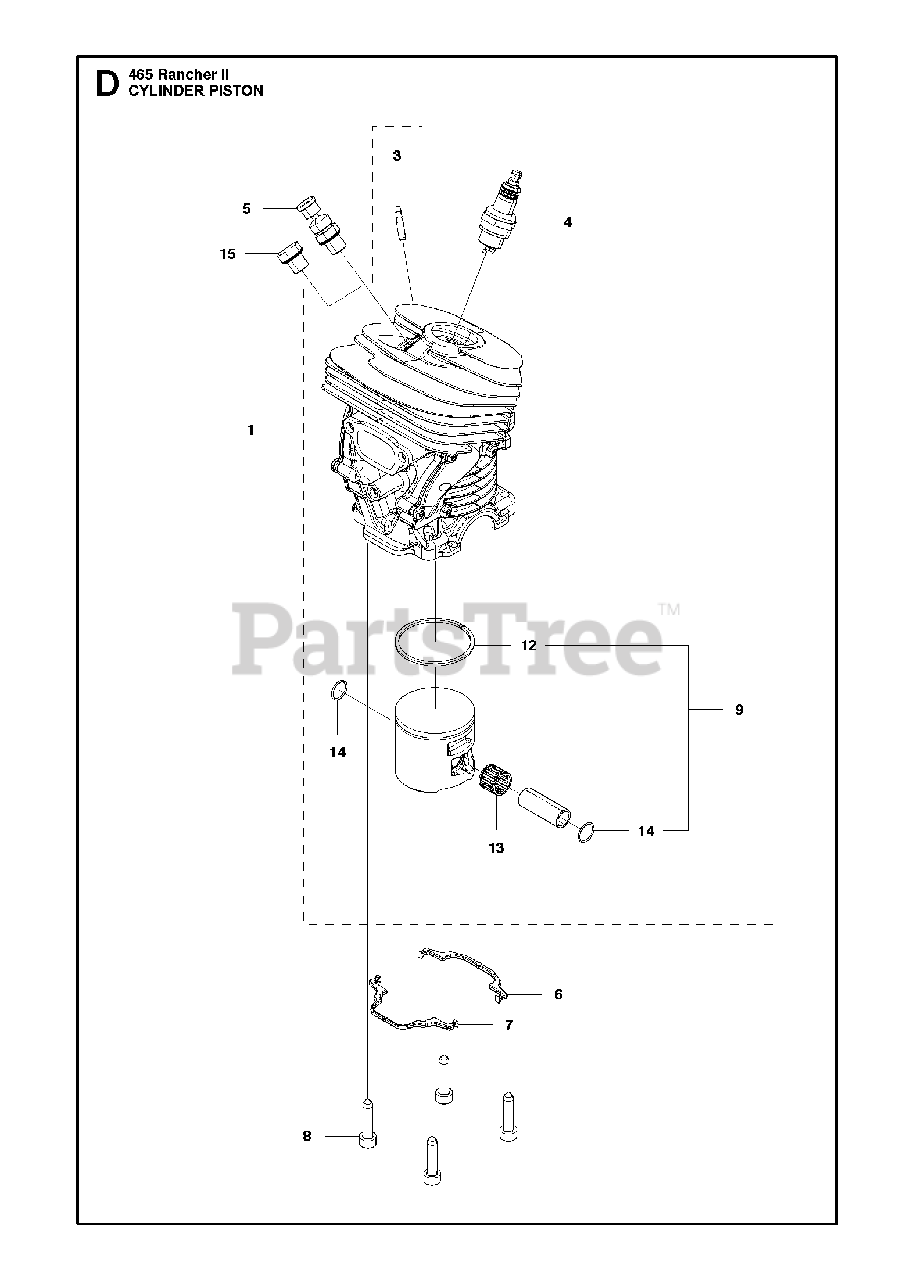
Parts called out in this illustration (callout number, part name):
1	CYLINDER-PISTON ASSY
3	FITTING
4	BPMR7A NGK SPARK PLUG
9	PISTON ASSY
12	PISTON RING
13	SUPPORT BUSHING
14	CLIP
15	CYLINDER PLUG
